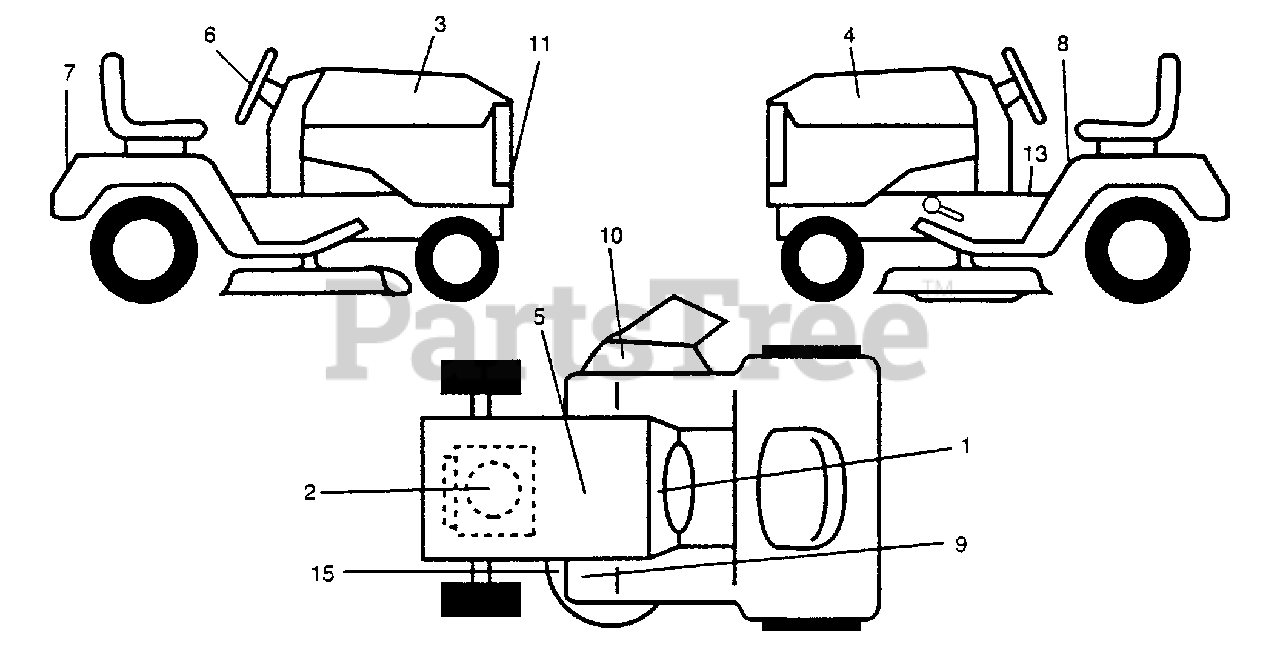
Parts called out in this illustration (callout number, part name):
1	Decal Instruction Dash Eng/fr
2	Decal HP Engine
3	Decal Hood RH
4	Decal Hood LH
5	Decal Caution Battery Fr/ger
6	Decal Insert Steering Wheel
8	Decal Caution Fender Eng/fr
9	Decal Clutch/brake Eng/fr
10	Decal Warning MULT-LANGUAGE
13	Decal Brake Parking Saddle
15	Decal V-Belt Sch 44/50
